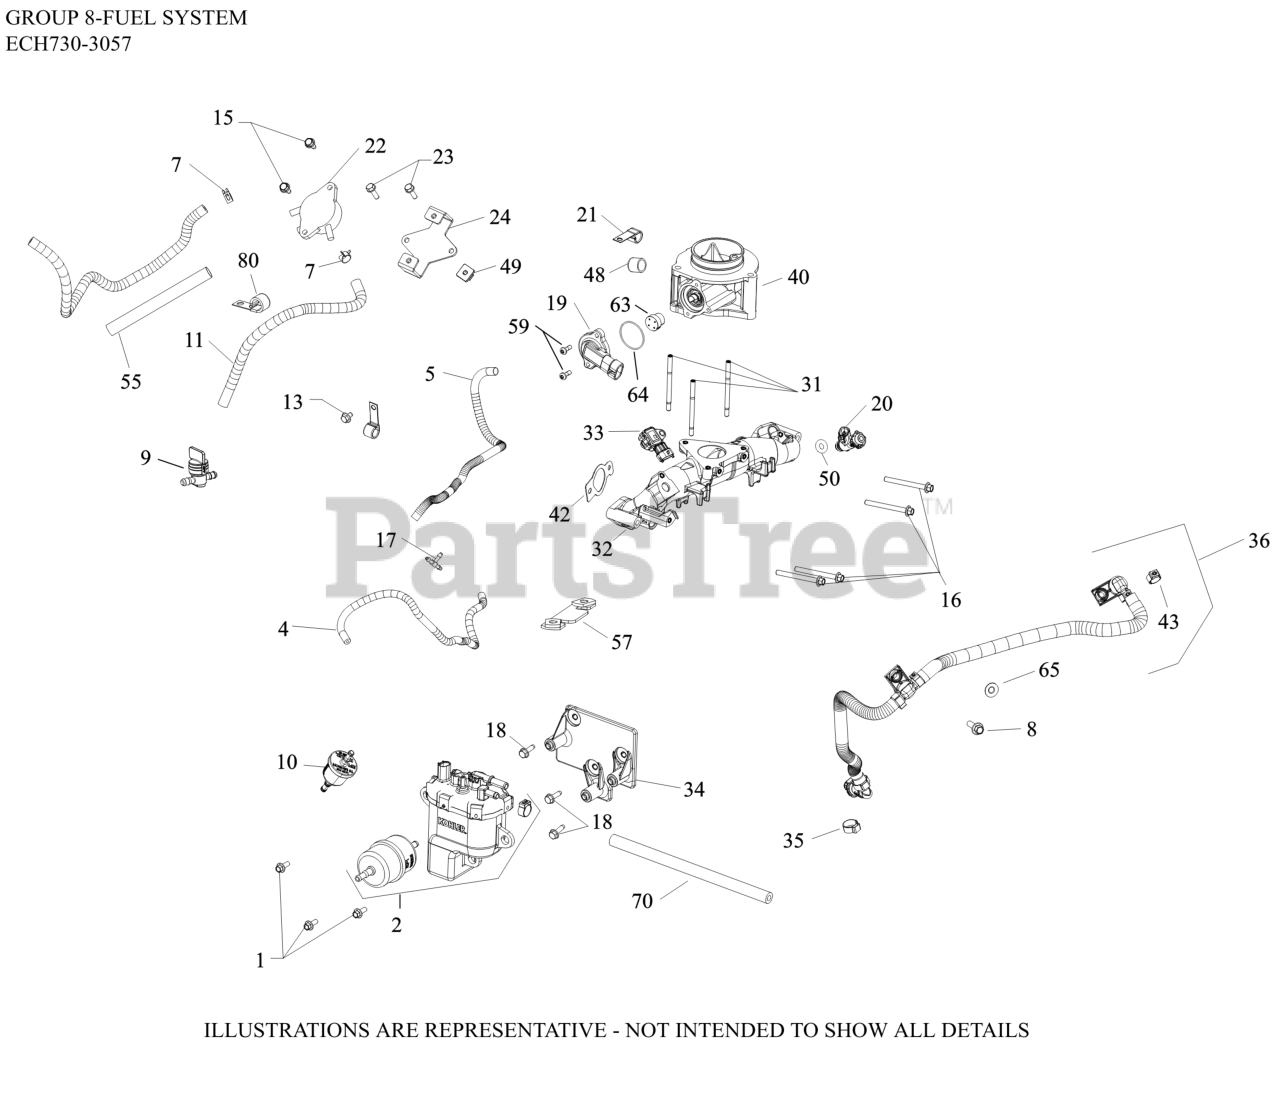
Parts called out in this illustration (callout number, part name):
1	SCREW, FLG M6X1.0X16
2	FUEL PUMP
2	KIT,FP MODULE (ECH/ECV 440,630,940)
4	HOSE, EVAPORATIVE (15.0)
5	SLEEVE, ANTI-ABRASION
7	CLAMP, HOSE (KM)-USE 25 237 31-S
8	SCREW, FLG M6x1.0x20
10	FILTER, FUEL
11	HOSE,LW PERM.FUEL 24.00"-USE 25 111 81-S
13	SCREW, THREAD FORMING
15	SCREW, THREAD FORMING
16	SCREW, FLG M6X1.0X60
17	TEE CONNECTOR
18	SCREW, THREAD FORMING
19	SENSOR, THROTTLE POSITION
20	INJECTOR, FUEL
21	CLIP, CABLE
22	PUMP, FUEL
23	SCREW, TAP M6X1.7X18
24	BRACKET, FUEL PUMP MOUNTING
31	STUD,M6X1.0X84
32	KIT, MANIFOLD
33	SENSOR, T-MAP
34	BAFFLE, FUEL MODULE
35	CLAMP, HOSE
36	FUEL HOSE ASSEMBLY,ECH680-ECH749
40	BODY, THROTTLE ASM W/ PIN (30)
42	GASKET, INTAKE MANIFOLD-USE 24 041 79-S
43	CLAMP, OETIKER
48	CAP, MASKING
49	NUT, PLASTIC - BLACK
50	KIT, FUEL INJECTOR O-RING
55	SLEEVE, ANTI ABRASION -USE 25 431 12-S
57	BRACKET, MOUNTING
63	MAGNET ASSEMBLY, TPS
64	O-RING, TPS SENSOR
65	CLIP, RETAINER
70	HOSE, FUEL LOW-PERMEATION
NI	CLIP, CABLE (KM)
